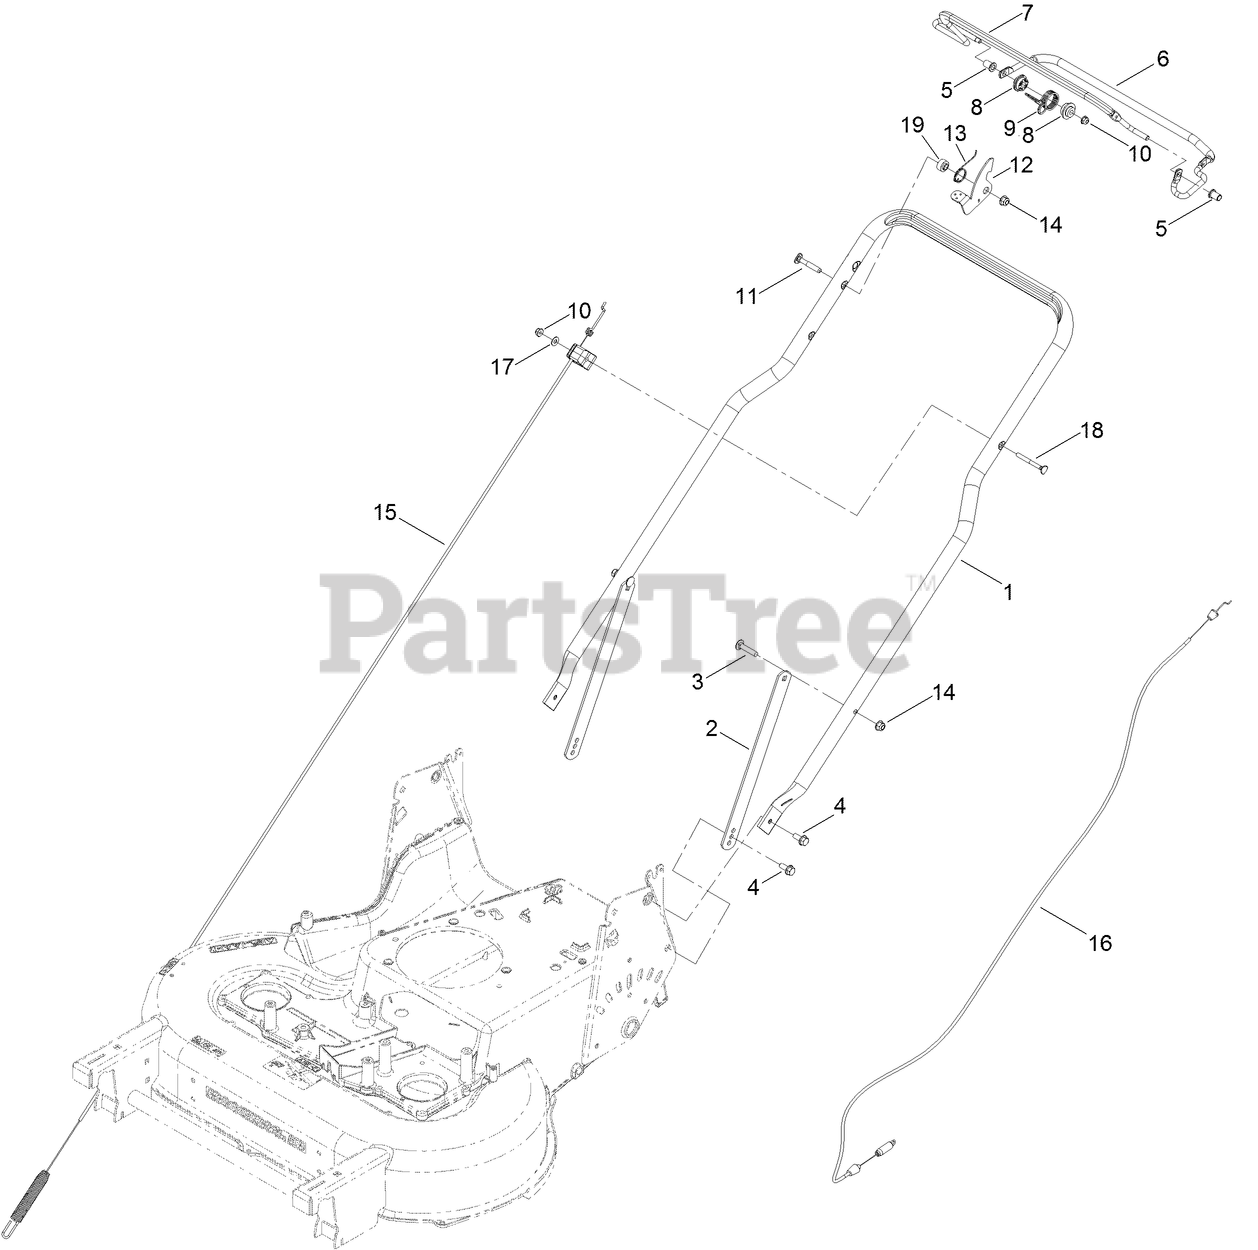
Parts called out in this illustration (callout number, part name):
2	SUPPORT-HANDLE
3	BOLT-CARR
4	SCREW-HHF
5	BUSHING-HANDLEBAR
6	BAIL-DRIVE COATED
8	BUSHING-SPRING, PIVOT
9	SPRING-RETURN, BBC
10	NUT-HF
11	SCREW-HANDLE
12	LEVER-BBC
13	SPRING-LEVER, BBC
14	NUT-HF, NI
15	CABLE-BRAKE, 30" 2-BAIL
16	CABLE-TRACTION
17	WASHER-FLAT
18	SCREW-HANDLE
19	BUSHING-STEPPED
